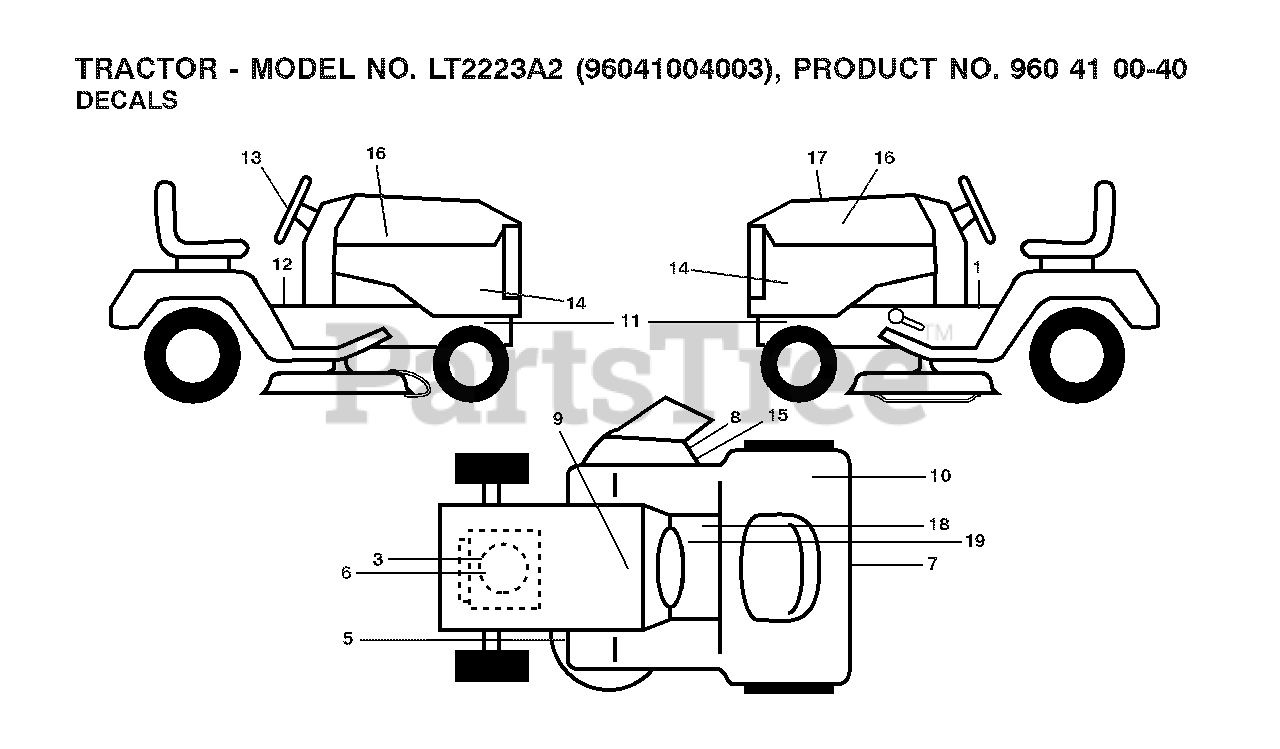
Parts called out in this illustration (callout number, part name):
5	DECAL.MOWER.SCH.48/54
8	DECAL.INTERNATIONL.CUTFINGER
9	DECAL BTRY SYMBOLS
10	DECAL.FENDER
15	DECAL, DEFLECT WARNING
19	DECAL PARK BRAKE
